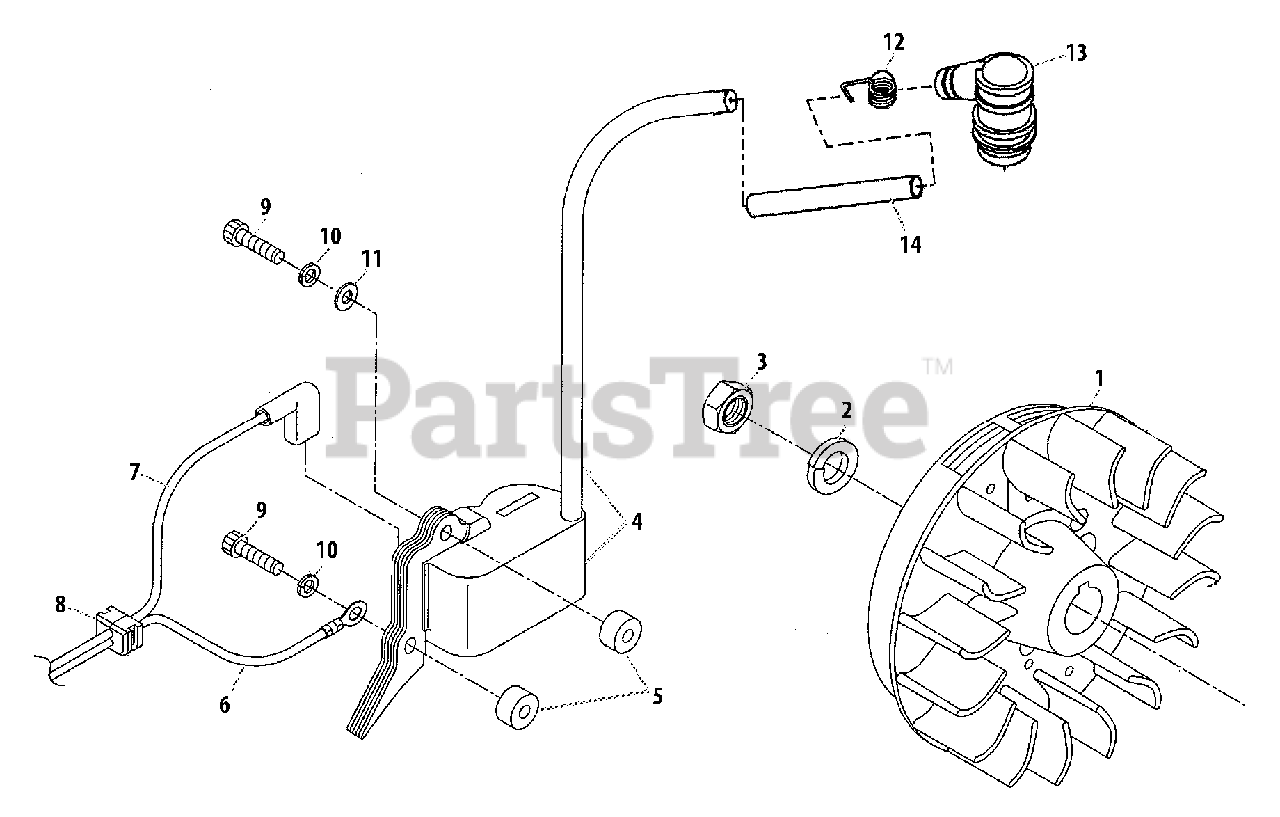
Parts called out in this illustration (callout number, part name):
1	FLYWHEEL
2	WASHER, SPRING 10
3	NUT 10×1.25
4	COIL ASSY, IGNITION
5	INSULATOR 4.2×11×6
7	WIRE, LEAD
8	GROMMET
9	BOLT M4×24
10	WASHER, SPRING 4 MM
11	WASHER 4.3×9.6×0.8
12	TERMINAL, SPARK PLUG
13	CAP, SPARK PLUG
14	TUBE, PROTECTIVE
